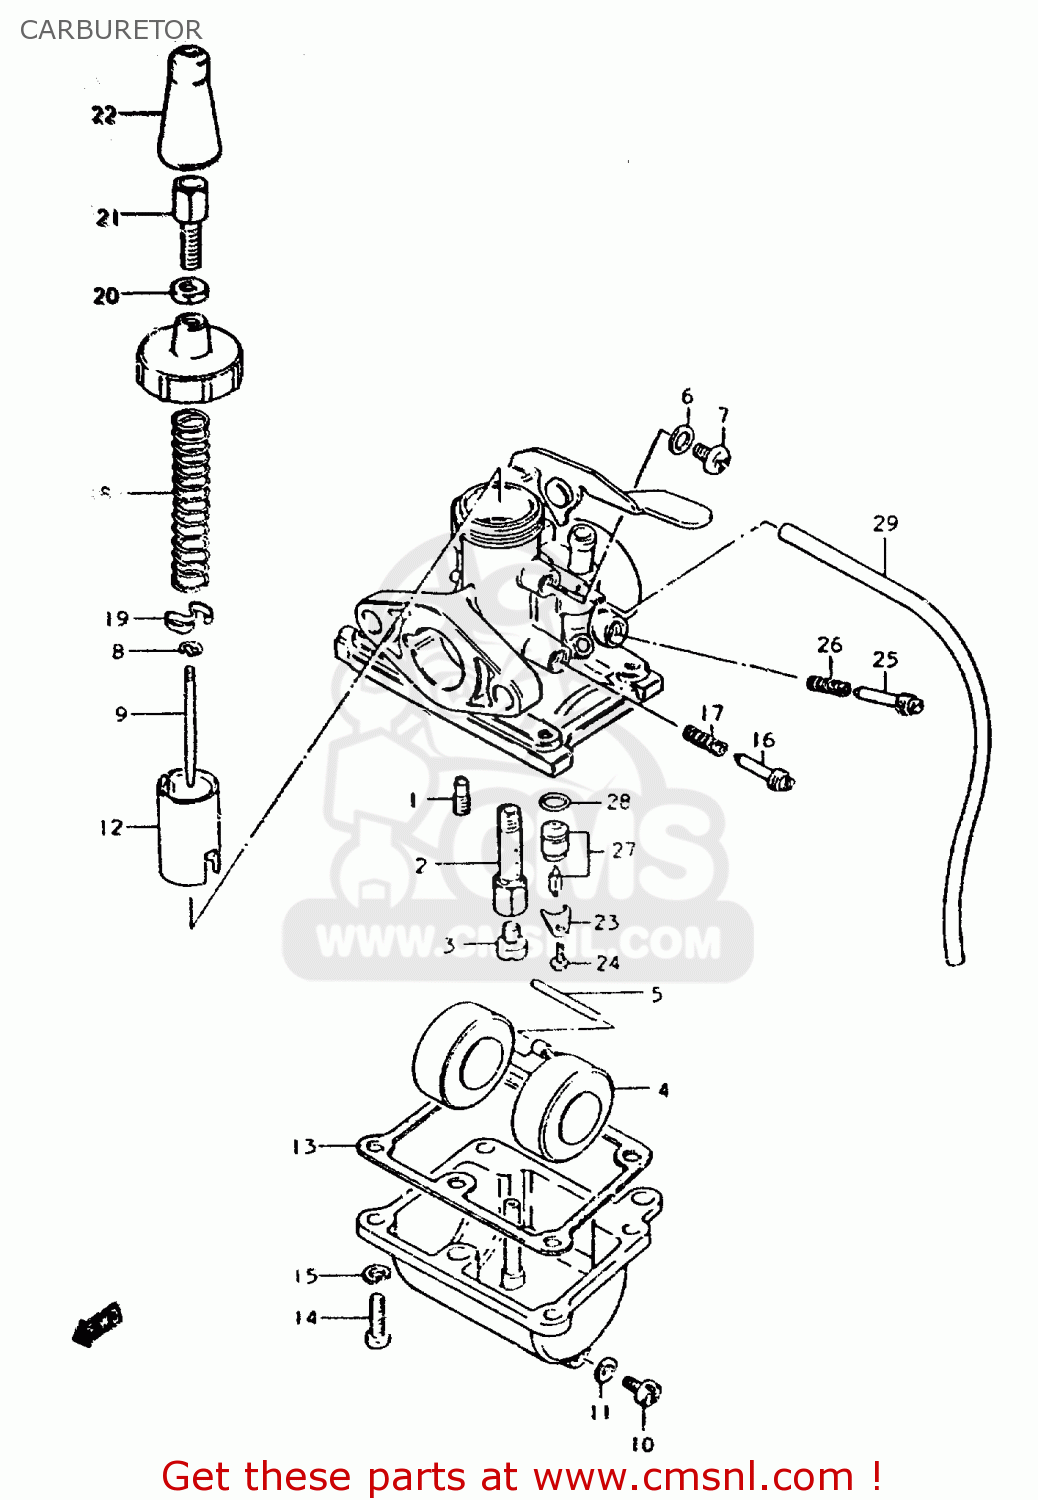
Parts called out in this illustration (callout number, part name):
1	JET,PILOT
2	JET, NEEDLE (E-4)
3	JET,MAIN(65)
4	FLOAT
5	PIN,FLOAT
6	RING
7	SCREW
8	CLIP,NEEDLE
9	NEEDLE, JET (3L14-3)
10	PLUG
11	GASKET,DRAIN,PLUG (NAS)
12	VALVE, THROTTLE (CA:1.5)
13	GASKET,FLOAT CHAMBER (NAS)
14	SCREW
15	LOCK WASHER
16	SCREW,THROTTLE STOP
17	SPRING
18	SPRING,THROTTLE VALVE RETURN
19	PLATE,THROTTLE VALVE
20	NUT
21	ADJUSTER,CABLE
22	CAP,CABLE ADJUSTER
23	PLATE,NEEDLE VALVE FITING
24	SCREW
25	SCREW,AIR
26	SPRING
27	VALVE ASSY,NEEDLE
28	O RING
29	HOSE
